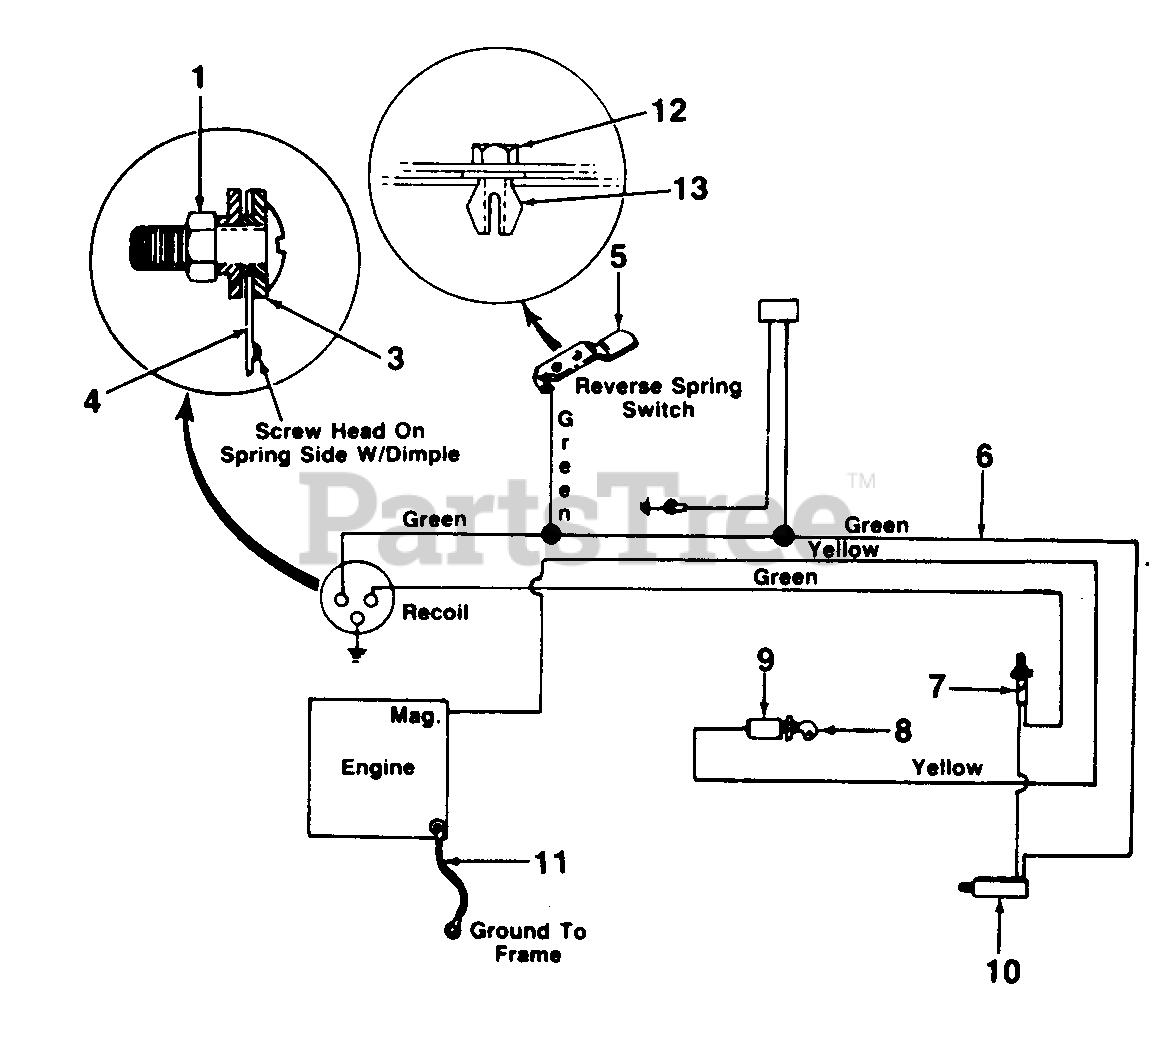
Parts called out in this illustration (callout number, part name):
1	Hex Nut #10-24 Thd.
3	Fiber Washer
4	Switch Spring-Recoil
5	Spring Switch-Reverse
6	Wire Harness
7	Safety Switch-Red N.C.- Clutch
8	Ignition Key
9	Ignition Switch
10	Safety Switch-P.T.O.
11	Ground Wire
12	Truss Mach. Scr. #10-24
13	Push-ln Nut #10
